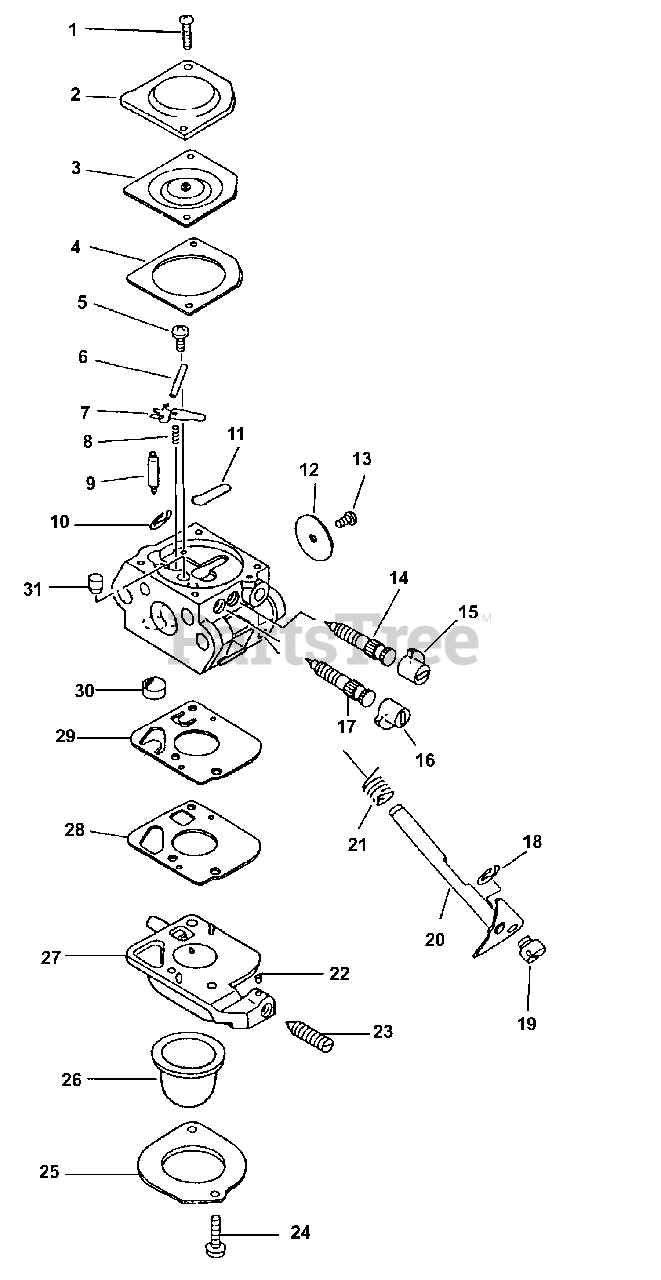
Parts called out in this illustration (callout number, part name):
2	COVER, METERING DIAPHRAGM
3	DIAPHRAGM, METERING
4	GASKET, METERING
6	PIN, METERING LEVER
7	LEVER, METERING
11	PLUG, WELCH
12	VALVE, THROTTLE
14	NEEDLE, LOW SPEED
15	CAP, LIMITER - WHITE
16	CAP, LIMITER - RED
17	NEEDLE, HIGH SPEED
20	SHAFT, THROTTLE
21	SPRING, THROTTLE RETURN
22	PIECE, FRICTION
23	SCREW, IDLE ADJUST
25	RETAINER
26	BULB, PURGE
27	BODY ASSY, PURGE
30	STRAINER
31	NOZZLE, CHECK VALVE
A	REPAIR KIT, CARBURETOR
B	GASKET / DIAPHRAGM KIT
